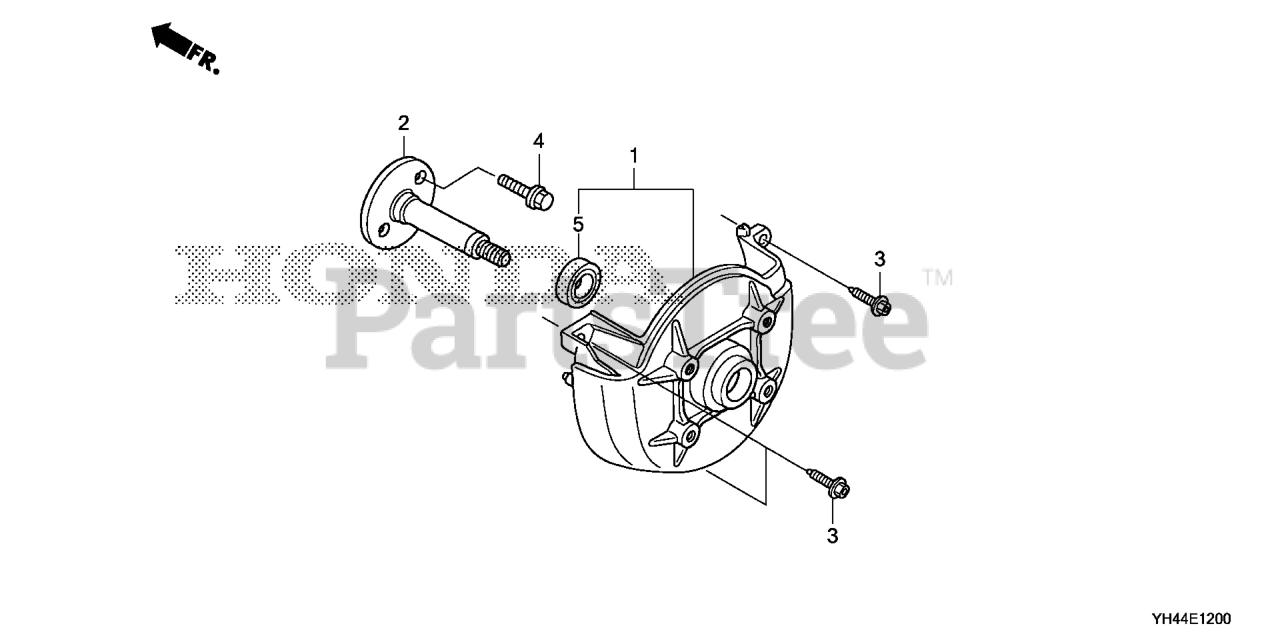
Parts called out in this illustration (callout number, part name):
1	COVER, FAN
2	SHAFT, P.T.O.
3	BOLT, SOCKET (5X20)
4	BOLT, FLANGE (6X22)
5	BEARING, RADIAL BALL (6001UU) (SOURCE: VINTAGE PARTS INC.)
